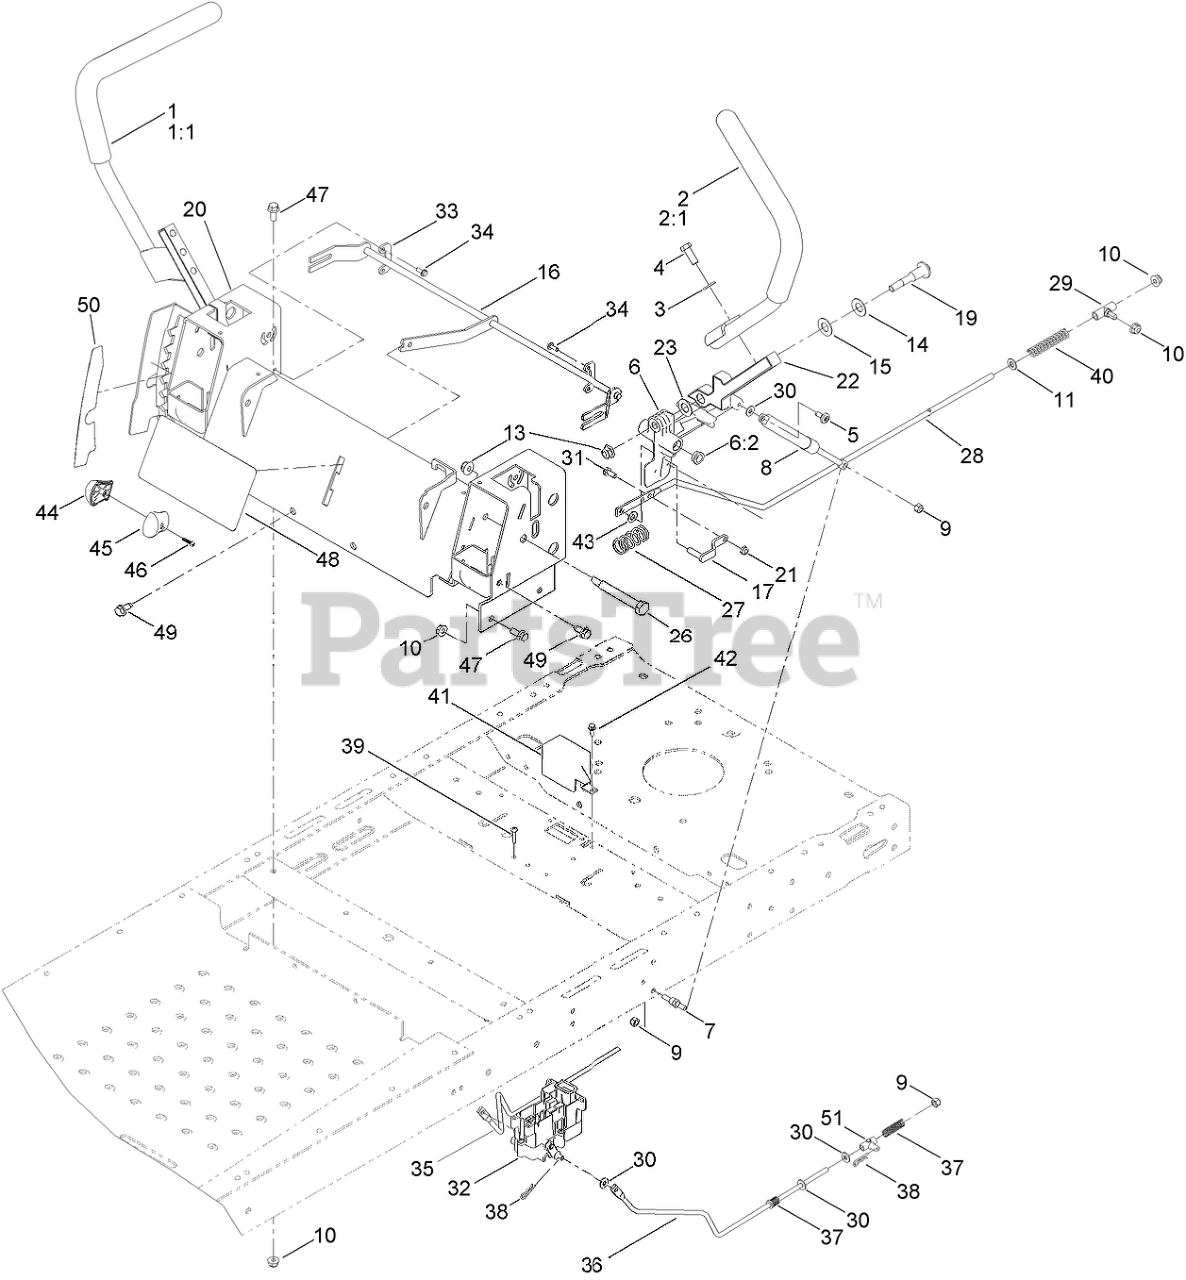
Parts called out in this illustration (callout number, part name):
1	HANDLE-CONTROL, RH
2	HANDLE-CONTROL, LH
3	WASHER-FLAT
4	SCREW-HH
5	SCREW-SHOULDER
6	ACTUATOR ARM ASM
6:2	BUSHING-FLANGE
7	STUD-DAMPER
8	Damper-Control, Motion
9	NUT-LOCK, NI
10	NUT-HF, NI
11	WASHER-PLAIN
13	NUT-HF, NI
14	WASHER-BELLEVILLE
15	WASHER
16	CONTROL-SPEED
17	PIN-ROD, HYDRO
19	BOLT-PIVOT
20	CONTROL BOX ASM
21	NUT-LOCK, NI
22	LEVER-CONTROL
23	WASHER-NYLON
26	BOLT-PIVOT
27	SPRING-RETURN
28	ROD-HYDRO
29	MOUNT-ROD, HYDRO
30	WASHER
31	SCREW-HH
32	BRAKE CONTROL MODULE ASM
33	RETAINER
34	SCREW-TAPTITE
35	ROD-BRAKE, RH
36	ROD-BRAKE, LH
37	SPRING-COMPRESSION
38	PIN-COTTER
39	SCREW-PPH
40	SPRING-RETURN, NEUTRAL
41	COVER-BRAKE
42	SCREW-HWH
43	SPACER-NYLON
44	KNOB-RH
45	KNOB-LH
46	SCREW-PPH
47	SCREW-HHF
48	DECAL-SPEED CONTROL
49	SCREW-HWHTF
50	DECAL-HOC
51	MOUNT-PIVOT
